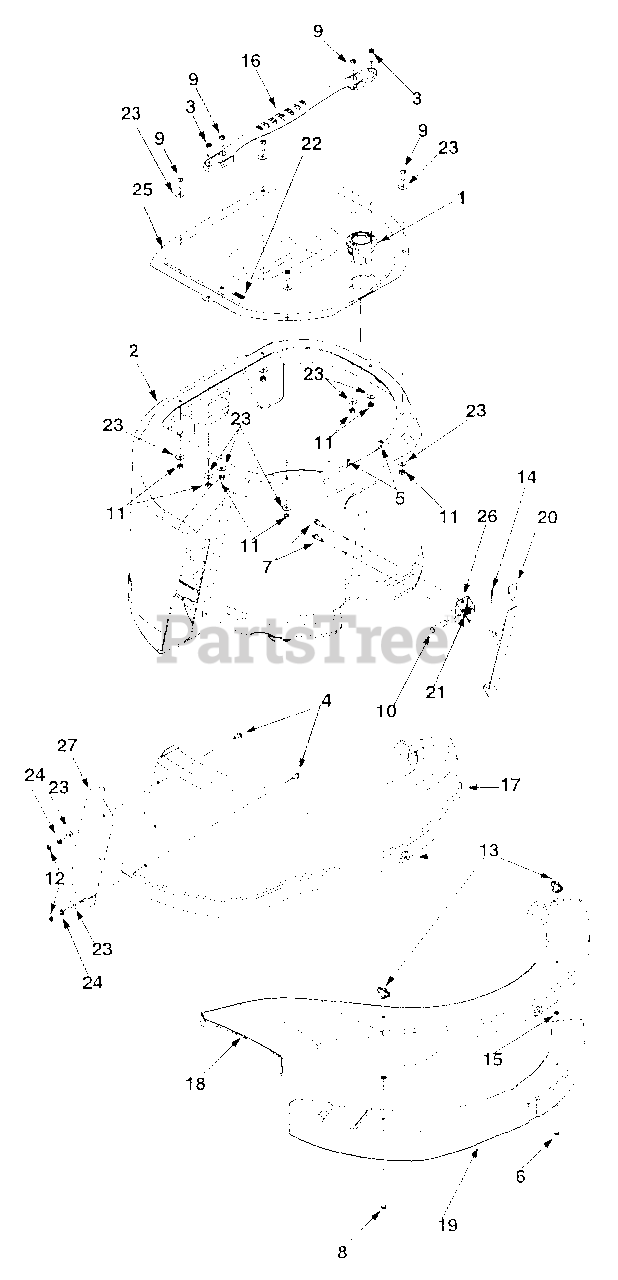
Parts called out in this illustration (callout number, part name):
1	Flow Indicator Assembly
2	Grass Bag Assembly
3	Machine Screw 1/4-20 x 1.0
4	Machine Screw 1/4-20 x 0.5"
5	Hex Screw #10-16 x 0.5"
6	Hex Screw 1/4-20 x 2.75"
7	Self-Tapping Screw 1/4-20 x 0.75"
8	Hex Screw 1/4-20 x 3.75"
9	Machine Screw 1/4-20 x 0.75"
10	Clevis Pin
11	Hex Sems Nut 1/4-20
12	Jam Nut
13	Wing Nut
14	Cotter Pin
15	Speed Nut
16	Bag Handle
17	Discharge Chute: Grass Bag
18	Side-Discharge Chute
19	Mulching Plug
20	Bag Release Lever
21	Torsion Spring
22	Clip Spring
23	Flat Washer
24	Lock Washer
